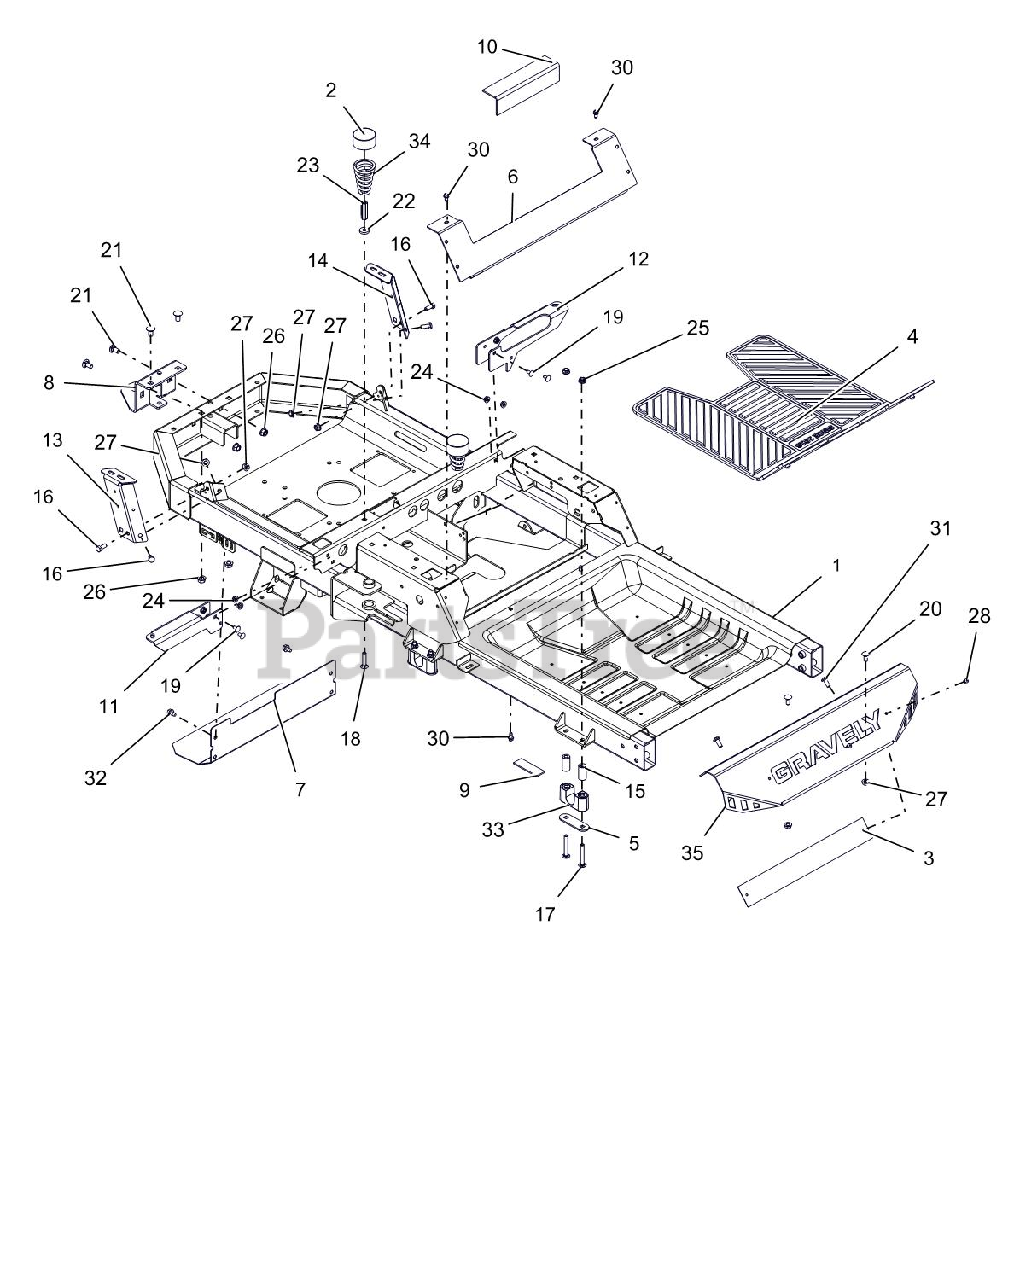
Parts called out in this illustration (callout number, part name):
1	KIT, ZT-X/XL FRAME SERVICE
3	PLATE, BACK FOOT-REST XL
4	FLOOR MAT, RUBBER - GRAVELY
5	PLATE, BEARING SUPPORT
6	PLATE, SEAT KICK
7	HEAT, SHIELD
8	BRKT, HITCH TONGUE
9	PAD,RBR 1.0"X3.0" W/ADHESIVE
10	PAD, RUBBER-TANK
11	BRKT,CROSS EXTENSION - LH
12	BRKT,CROSS EXTENSTION - RH
13	MOUNT,FENDER-RH EXTENSION
14	MOUNT,FENDER-LH EXTENSION
15	SPACER, .323 X .698 X 1.441
16	@BLT-HEX .31-18X.75 GR5 YWZC
17	BLT-RDHDSQSHNK .31-18X2.25 YWZ
18	@BLT-RDHDSQNK .31-18X1.50 G5YZ
19	BLT-RDHDSQSHNK.25-20X.50 YWZC
20	@BLT-RDHDSQNK .31-18X.75 G5YZ
21	@BLT-RDHDSQNK .38-16X.75 G5YZ
22	WSHR-FL-STL .328X.87X.179 YWZC
23	NUT, COUPLING 5/16-18 X 1 3/4
24	NUT-LK-CTR-FLG .25-20 YWZC
25	@NUT-LK-CTR-FLG .31-18 YZ GR F
26	@NUT-LK-TOP-FLG .38-16 YWZC
27	NUT-LK-TOP-FLG .31-18 YWZC
28	RIVET, .1875 AL/AL .126-.250
30	SCR-TAP .25-20X.50 HWH TR YWZ
31	SCR-RDHDSKTAP .31-18 X .75
32	@SCR-TAP .31-18X.50 HWH TR YWZ
33	BSHG, DECK LIFT PIVOT
34	SPRING, SEAT
35	KIT, FOOTPLATE W/DECAL-ZTX
